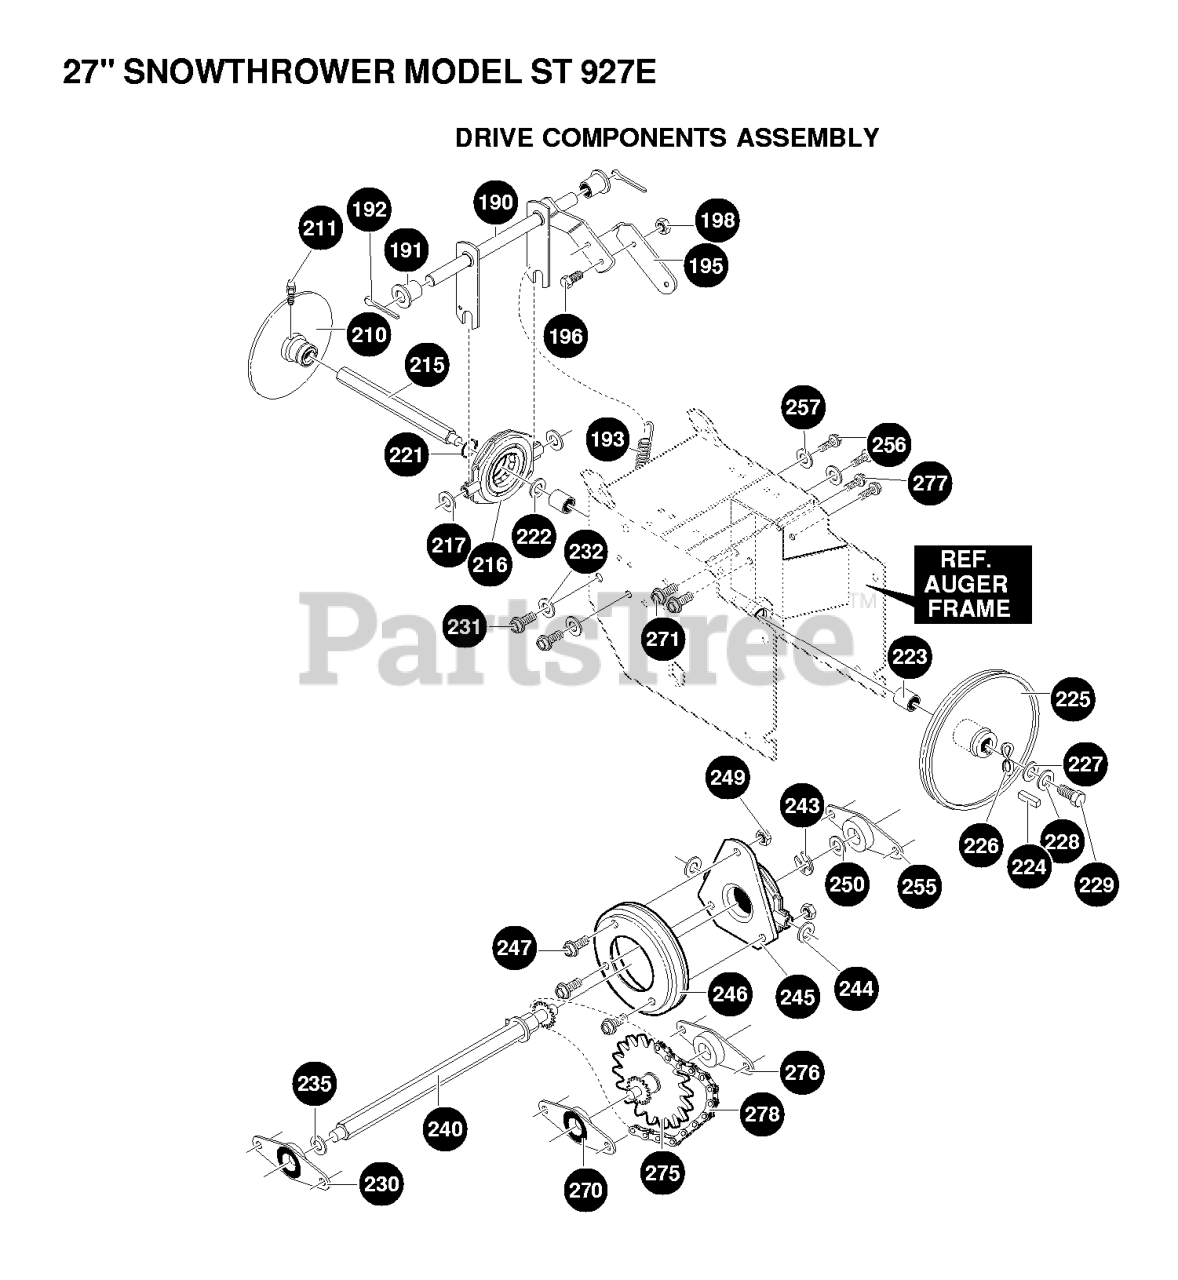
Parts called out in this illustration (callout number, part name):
191	FLANGE BEARING
192	COTTER PIN .125 X 1.0
198	NUT, 1/4-20 REGHEXCTRLK
210	DISC, ASSY FRICWHL
211	GREASE FITTING
223	BEARING
224	SQUARE KEY
227	WASHER, FLAT .281X1.00X.
228	WASHER, REGSPTLK.263X.49X
229	SCREW, 1/4-20X .75 HHC
230	BEARING & RETAINER ASSY
231	SCREW, 5/16-18X .50 WAHHT
232	WASHER, HVSPTLK .328X.60X
240	HEX, ASSY #40-8T
243	RING, RETEX
245	BEARING, TRUNION CLUTCH
246	FRICTION DISC
249	NUT, 1/4-20 HEX KEPS
255	BEARING & RETAINER ASSY
256	SCREW, 5/16-18X .50 WAHHT
257	WASHER, HVSPTLK .328X.60X
270	BEARING & RETAINER ASSY
271	SCREW, 5/16-18X .50 WAHHT
275	JACK, ASSY #41 - 36T & 7T
276	BEARING & RETAINER ASSY
277	SCREW, 5/16-18X .50 WAHHT
